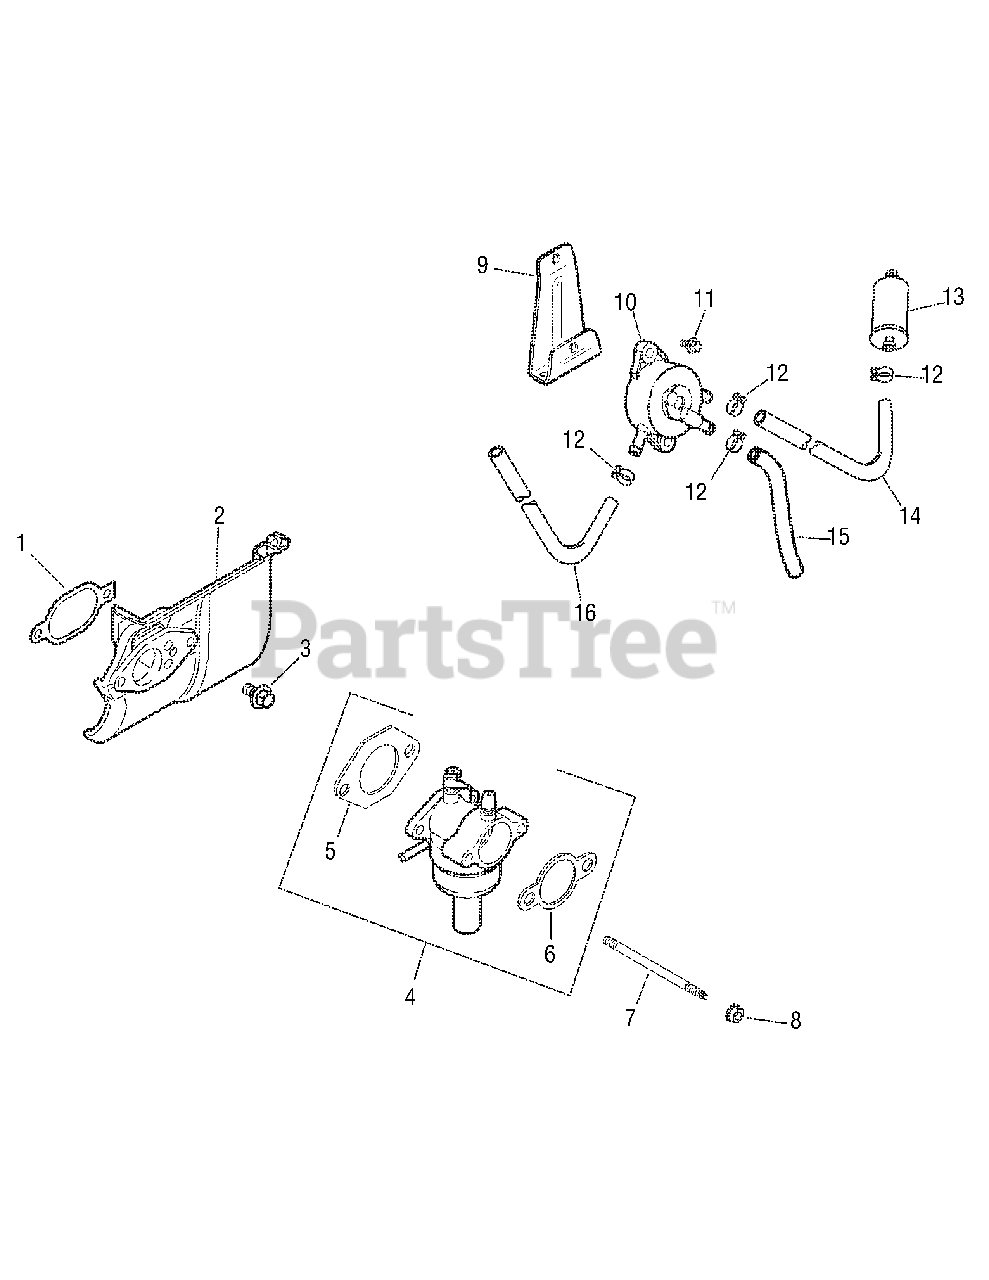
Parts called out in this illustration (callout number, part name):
1	Gasket, heat deflector
2	Deflector, heat
3	Screw, hex. flange M6x1.0x20
4	Carburetor w/gaskets (Includes 5,6)
5	Gasket, carburetor
6	Gasket, air cleaner
7	Stud, carburetor mounting
8	Nut, hex. flange M6x1.0
9	Bracket, fuel pump mounting
11	Screw, hex. flange
12	Clamp, hose
13	Filter, fuel
14	Line, fuel 15-3/4" (pump to filter)
15	Line, fuel 2" (pump to carb)
16	Line, fuel 10" (pump to fitting)
